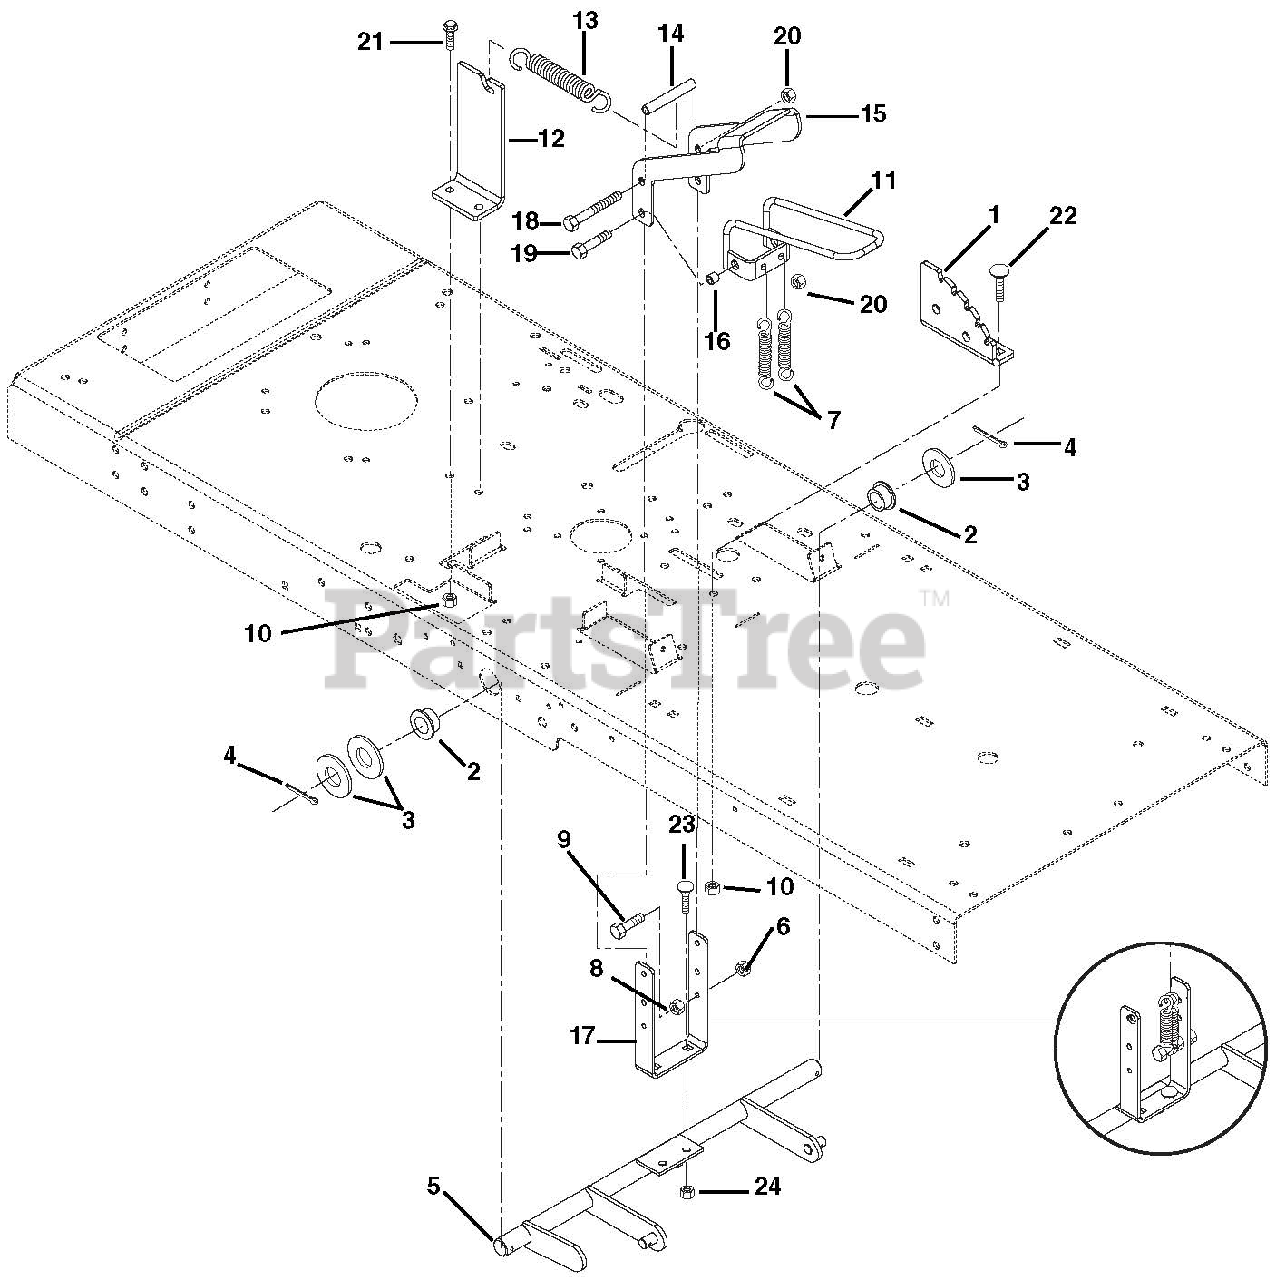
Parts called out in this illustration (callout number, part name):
1	DETENT, PLATE
2	BSHG-FLG1.020X1.385X.75X1.75NY
3	WSHR-FL-STL- 1.062X2.0X.134 YZ
4	@PIN-CTR .18X1.50 EXTPRSQCT YZ
5	LIFT, WLDM'T
6	@NUT-LK-CTR .25-20 YWZC
7	SG-TENS .092X.69X1.75 WLD 54
8	@NUT-HEX .25-20 YWZC
9	@BLT-HEX .25-20X2.00 GR5 YWZC
10	@NUT-LK-CTR .38-16 YWZC
11	RELEASE WLDM'T
12	BRACKET, LIFT
13	SG-TENS .187X1.50X9.94 WLD 40
14	SPACER .328 X .462 X 3.14
15	HANDLE, DECKLIFT
16	SPACER .328 X .462 X .410
17	BRACKET, HANDLE
18	@BLT-HEX .31-18X4.50 GR5 YWZC
19	@BLT-HEX .31-18X1.25 GR5 YWZC
20	@NUT-LK-NYL .312-18 YWZC
21	@BLT-HEX .38-16X1.00 GR5 YWZC
22	@BLT-RDHDSQNK .38-16X.75 G5YZ
23	@BLT-RDHDSQNK .38-16X1.00 G5YZ
24	@NUT-LK-TOP-FLG .38-16 YWZC
